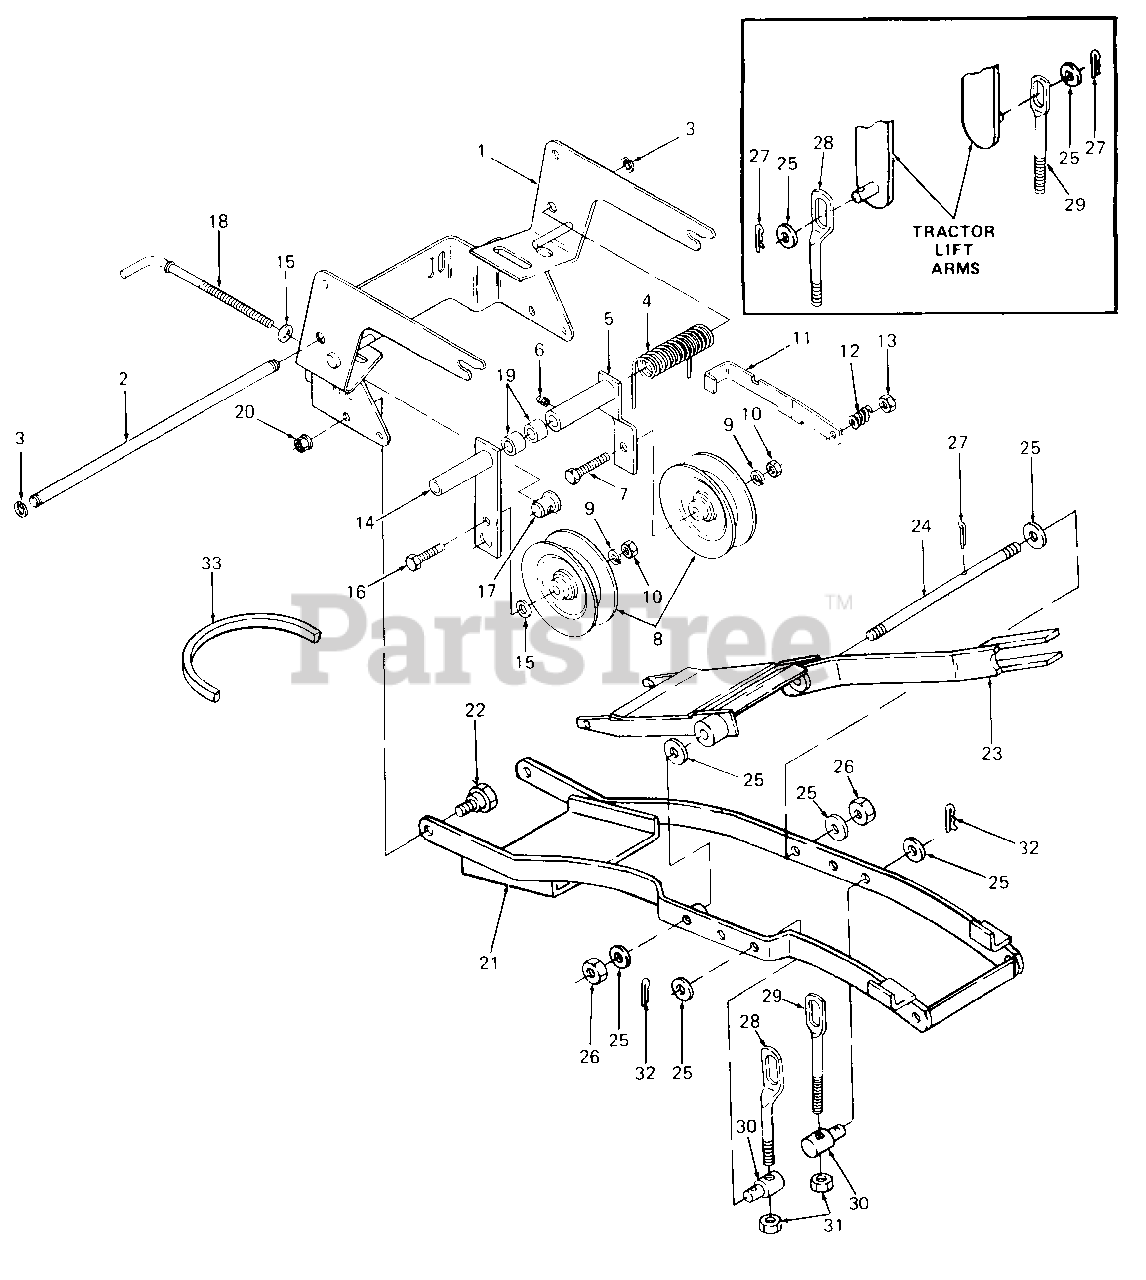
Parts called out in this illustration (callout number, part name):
4	Spring, Mule Drive
7	Screw, Hex Cap, 3/8-16 X 2.25 Lg GR5
8	Pulley, Idler
9	Washer, Lock, 3/8
10	Nut, Hex, 3/8-16 GR5
13	Nut, Hex Center Lock, 3/8-16
16	Screw, Hex Cap, 3/8-16 X 1.75 Lg GR5
17	Ferrule, Threaded
18	Rod, Adjusting
20	Nut, Hex Flanged Lock, 3/8-16
25	Washer, Flat, .510 X 1.0 X .060 Thk
26	Nut, Hex Jam w/Plastic Patch, 1/2-20
27	Pin, Cotter, 1/8 Dia X 1.25 Lg
28	Link, Adjustable Offset
29	Link, Adjustable
30	Ferrule, Adjustment
31	Nut, Hex Center Lock, 1/2-20
32	Pin, Cotter, 3/32 Dia X 1.00 Lg
33	Belt, PTO, B-Section X 107.8 Lg
